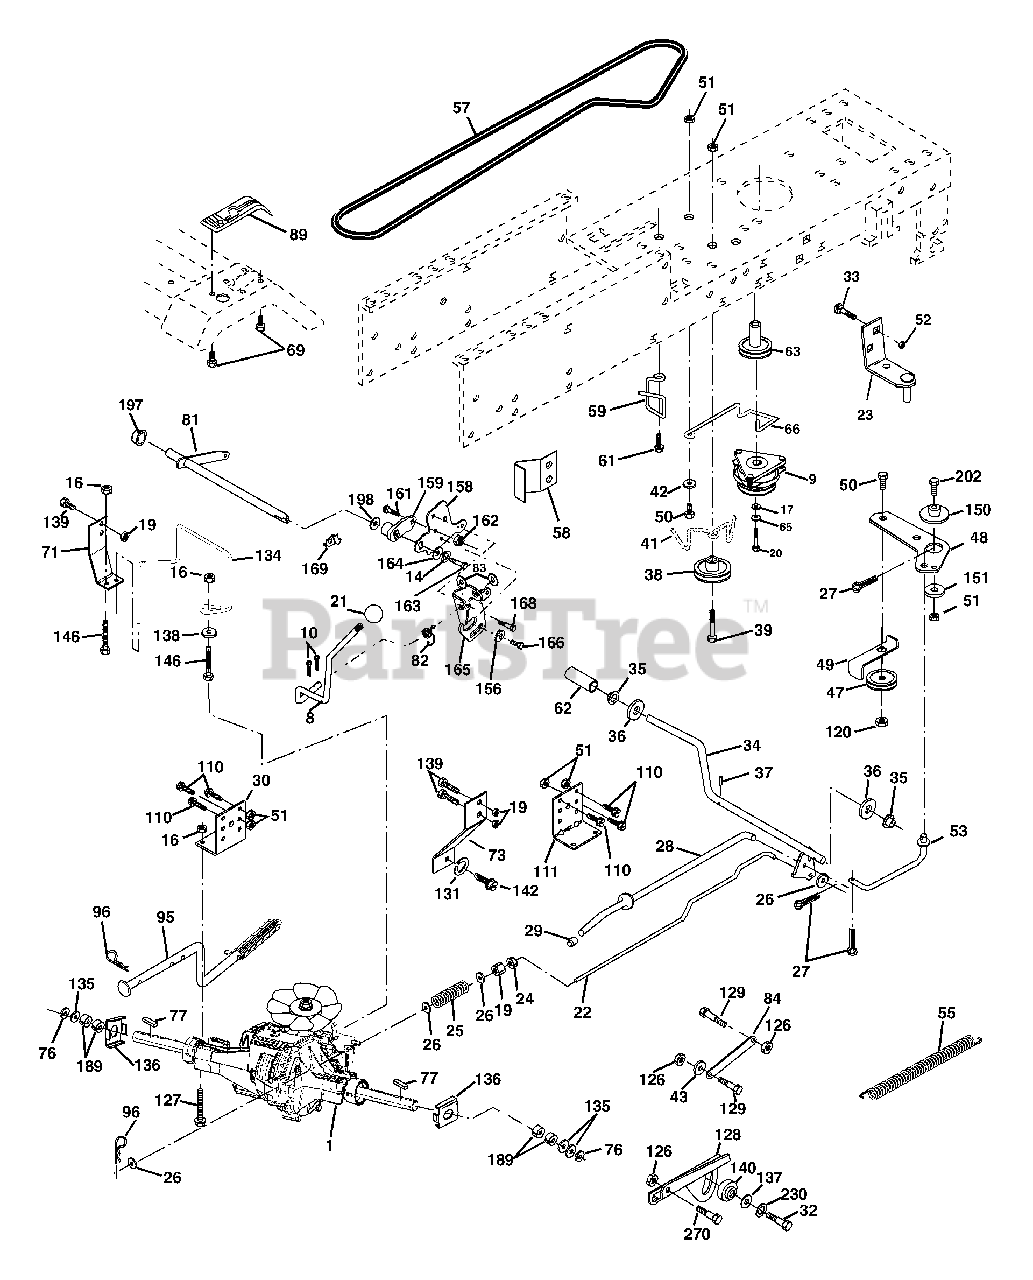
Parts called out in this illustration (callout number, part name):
8	Rod Shift Fender Adjust Yt
9	Clutch Electric
10	Pin, Cotter 1/8 x 1
14	Washer Lock Hvy Helical
16	Nut Lock Hex W/Ins. 5/16-18 Unc
17	Washer 1-1/2 OD x 15/32 ID x .250
19	Nut Lock Hex W/Wsh 3/8-16 Unc
20	Bolt Hex 7/16-20 x 4 x Gr. 5-1.5 THR
21	Knob
22	Rod, Brake
23	Bracket Anti-Rotation
24	Nut, Hex Jam 3/8-16
25	Spring, Rod, Brake
26	Washer 13/32 x 13/16 x 16 Ga.
27	Pin Cotter 1/8 x 3/4
28	Rod, Brake, Park
29	Cap, Brake, Parking Black
30	Bracket, Transaxle, L.H.
32	Bolt Fin Hex 5/16-18 Unc x 3/4
33	Bolt Rdhd Sqnk 3/8-16unc x 1
34	Shaft, Foot Pedal
35	Bearing, Nylon
36	Washer 21/32 x 1 x 16 Gauge
37	Pin, Roll 3/16 x 1
38	Idler, Flat
39	Bolt Rdhd 3/8-16 Unc x 3
41	Keeper, Idler
42	Washer 13/32 x 16/16 x 12 Gauge
43	Bolt Shoulder 5/16-18 Unc
47	Pulley, Idler
48	Bellcrank Clutch Grnd Drv Stl
49	Retainer, Belt
50	Bolt Carr Sh 3/8-16 x 1-1/2 Gr. 5
51	Nut Crownlock 3/8-16
52	Nut Hexflange Lock
53	Link, Clutch
55	Spring, Return, Clutch
57	V-Belt, Drive
58	Keeper, Belt, Transaxle, R.H.
59	Keeper, Center Span
61	Screw 3/8-16 x .875
62	Cover, Foot Pedal
63	Pulley, Engine
65	Washer, Lock Hvy Hlcl Spr 7/16
66	Keeper Belt Engine F-proof
69	Screw Hex Wsh Hi-Lo 1/4-1/2 Unc
71	Strap Torque Lh Hydro-3000
73	Strap Torque Rh Hydro-300
76	E-Ring
77	Key Square 1/4 x 2
81	Shaft Asm Cross Tapered
82	Spring, Torsion
83	Washer 17/32 x 3/4 x 16 Gauge
84	Link Transaxle
89	Console, Shift
95	Control Asm Bypass Hydro-3000
96	Retainer Spring 1" Zinc/Cad
110	Bolt Fin Hex 3/8-16unc x 3/4 Gr. 5
111	Bracket, Transaxle, R.H.
120	Nut Lock Flg 3/8-16 Unc
126	Nut Lock 5/16-18 Nc Thd
127	Bolt Hex Flghd 5/16-18 x 3.0 Gr.5
128	Bracket Neutral Adjust HG-3000
129	Bolt Shoulder 5/16-18 Unc
131	Washer Lock 5/16
134	Rod Actuator Bypass Hydo-3000
135	Washer 1-1/32 x 1-5/8 x 16 Gauge
136	Washer Axle Flange
137	Washer 11/32 x 3/4 x 12 Ga.
138	Washer 11/32 x 1.25 x 16. Ga.
139	Bolt Fin Hex 3/8-16 x 3/4
140	Bushing Pinion Sector
142	Bolt 5/16 x 24 x 1
146	Bolt Hex Flghd 5/16-18 x 2-1/4
150	Spacer
151	Washer 13/32 x 2 x 10 Ga.
156	Washer Srrted 5/16 ID x 1.125
158	Bracket Shift Mount
159	Hub Tapered Flange Shift Lt
161	Bolt Rdhd Sqnk 1/4-20 x 3/4 Gr. 5
162	Nut Crownlock 1/4-20 Unc
163	Bolt Hex Fin 1/4-20unc x 1 Gr. 5
164	Washer 5/8 x .281 x 10 Ga.
165	Bracket Pivot Lever
166	Screw 5/16-18 x 5/8
168	Bolt Shoulder 5/16-18 x .561
169	Plate Fastening Lt
171	Screw Thdrol 3/8-16 x 1/2 Ty-Tt
189	Washer Spacer Axle
197	Nyliner Snap-In 5/8" Id
198	Washer Nyl 7/8 Id x .105
230	Washer Lock Hvy HLCL SPR 5/16
270	Bolt Hex Head 5/16-18 x 5/8 Gr. 5
